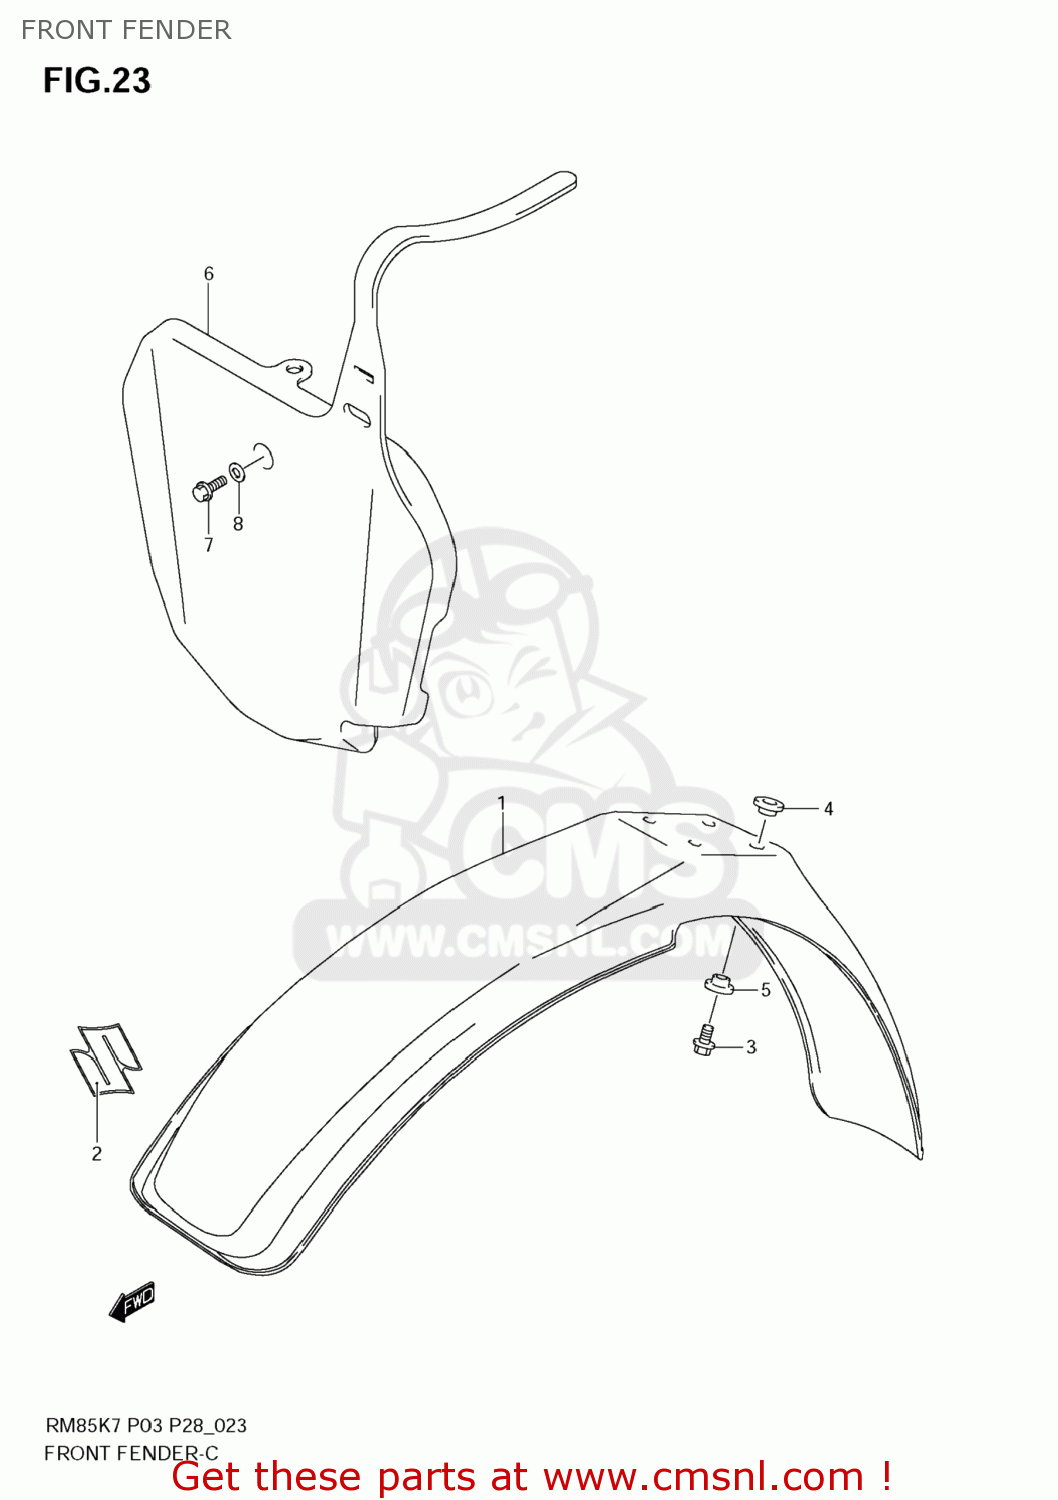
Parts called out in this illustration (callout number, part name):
1	FENDER,FR
2	EMBLEM,S
3	BOLT,6X20
4	WASHER
5	WASHER
6	PLATE,NUMBER FR
7	BOLT,6X20
8	WASHER(6.5X14X1.6)
